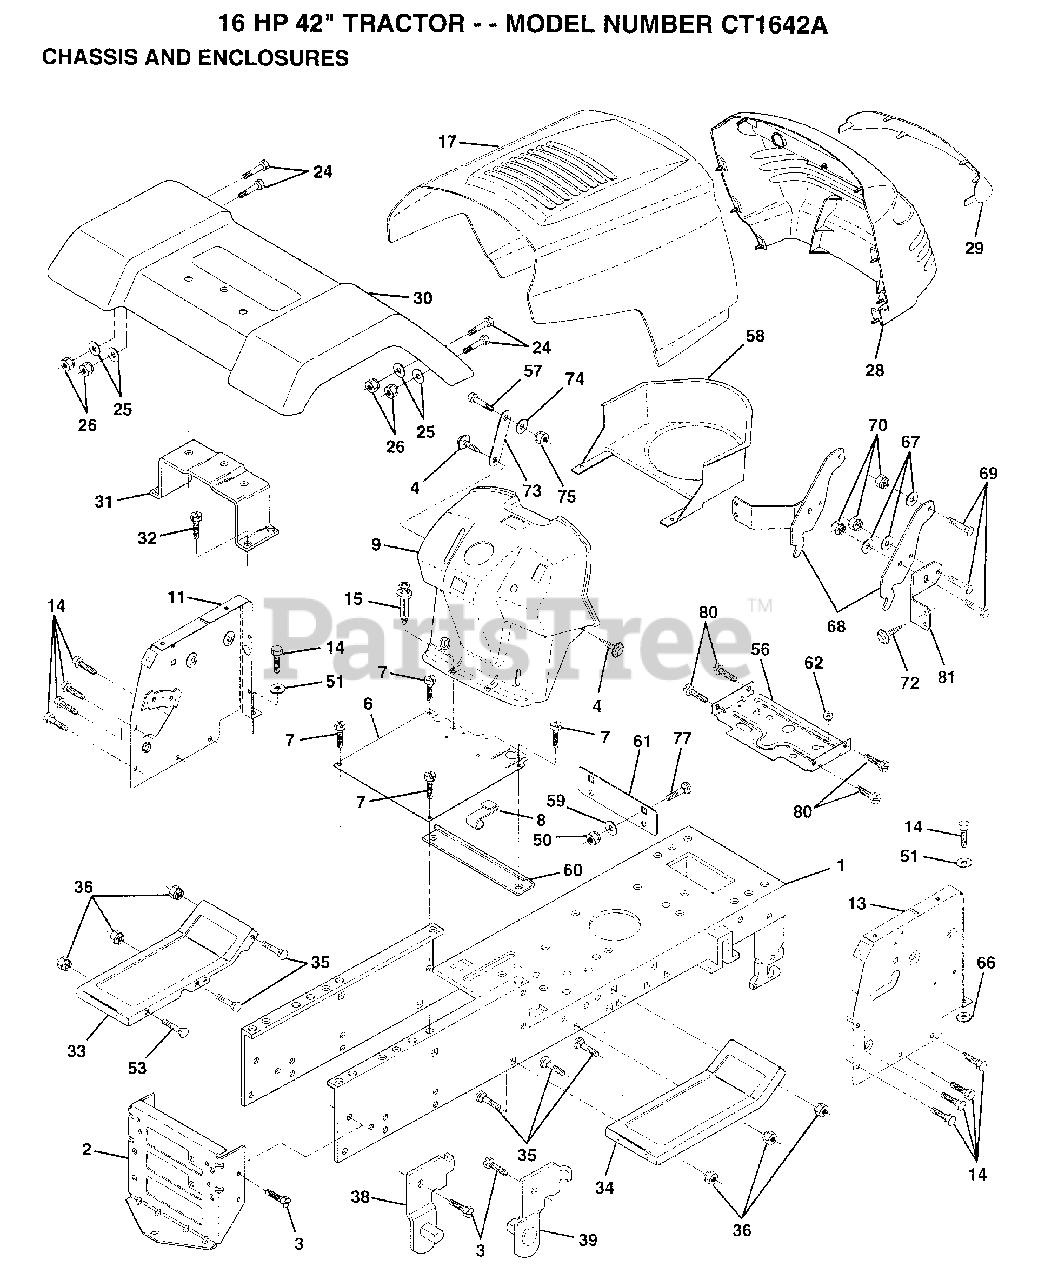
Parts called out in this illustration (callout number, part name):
3	SCREW
4	SCREW HEX CRT
7	SCREW
8	CLIP T
11	PANEL ASM DASH
14	SCREW LT
15	RIVET.PUSH.PLATE
17	HOOD.PNT.STEEL
24	BOLT
25	WASHER
26	NUT
29	LENS GRILLE
31	BRACKET SUPT FEND
32	SCREW
33	FOOTREST LH
34	FOOTREST
35	BOLT
36	NUT
38	BRACKET ASM LH
39	BRACKET ASM RH
50	NUT
51	WASHER
58	DUCT.AIR.B&S.18HP
59	WASHER
60	SPACER FENDER LT
61	PLATE EXTEN FEND
66	LOCKWASHER
67	WASHER
68	HING PICK-OFF HD
69	BOLT LT
73	BRACE SUPT DASH
74	WASHER
75	NUT
80	SCREW
81	BRACKET GRILLE
